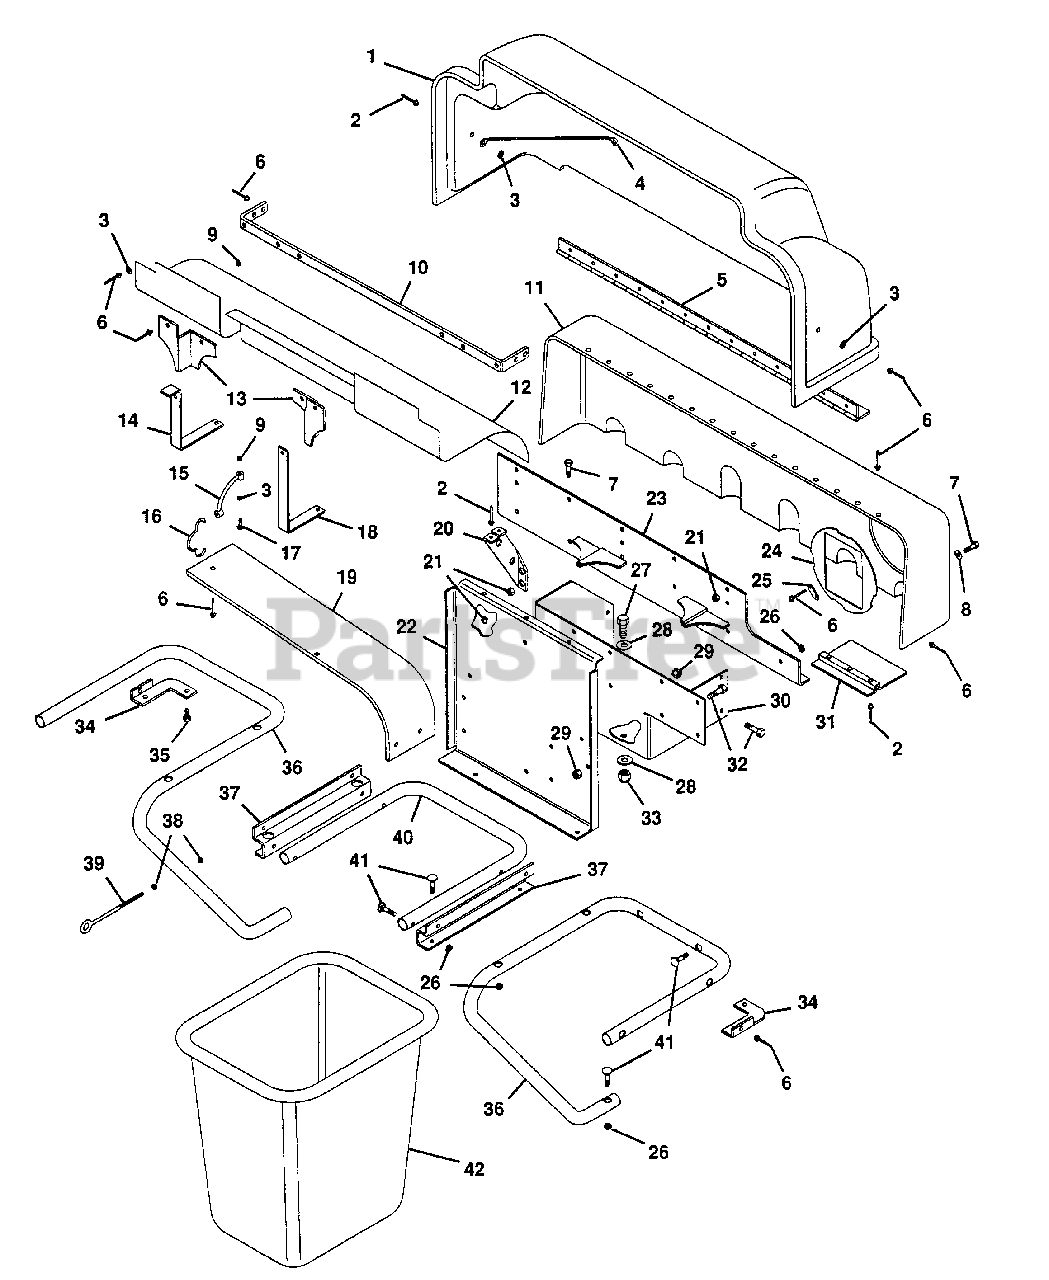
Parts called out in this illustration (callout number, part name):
1	Cover, Hinged
2	Rivet, Pop-Domed 3/16x.527
3	Washer, Flat .188x.562x.049
4	Brace
6	Rivet, Pop-Domed
7	Bolt, Hex 5/16-18x.875
8	Washer, Flat .340x1.12x.063
9	Nut, Lock 10-24
10	Bracket, Screen Mounting
11	Cover, Stationary
12	Screen
13	Baffle, L.H.
13	Baffle, R.H.
14	Brace
15	Strap
16	Hook
17	Screw, Mach. 10-24x1.00 Rd Hd
18	Brace
20	Brace
21	Nut, Lock 5/16-18
22	Bracket, Attachment
23	Weldment, Mounting Bracket
24	Plate, Adaptor
25	Clip, Boot
26	Nut, Lock 5/16-18
27	Bolt, Hex 1/2-13x1.25
28	Washer, Flat .531x.1.000x.063
29	Nut, Lock 3/8-16
30	Support, Bracket
31	Guide, Tube
32	Bolt, Hex 3/8-16x1.00
33	Nut, Lock 1/2-13
34	Bracket, R.H. Corner
34	Bracket, L.H. Corner
35	Bolt, Hex 5/16-18x.50
36	Tube, Right
36	Tube, Left
37	Bracket, Tube
38	Nut, Lock 1/4-20
39	Eyebolt
40	Tube, Center
41	Screw, Machine 5/16-18x1.50
42	Basket, Grass Bagger
NS	Decal, Gravely Logo
